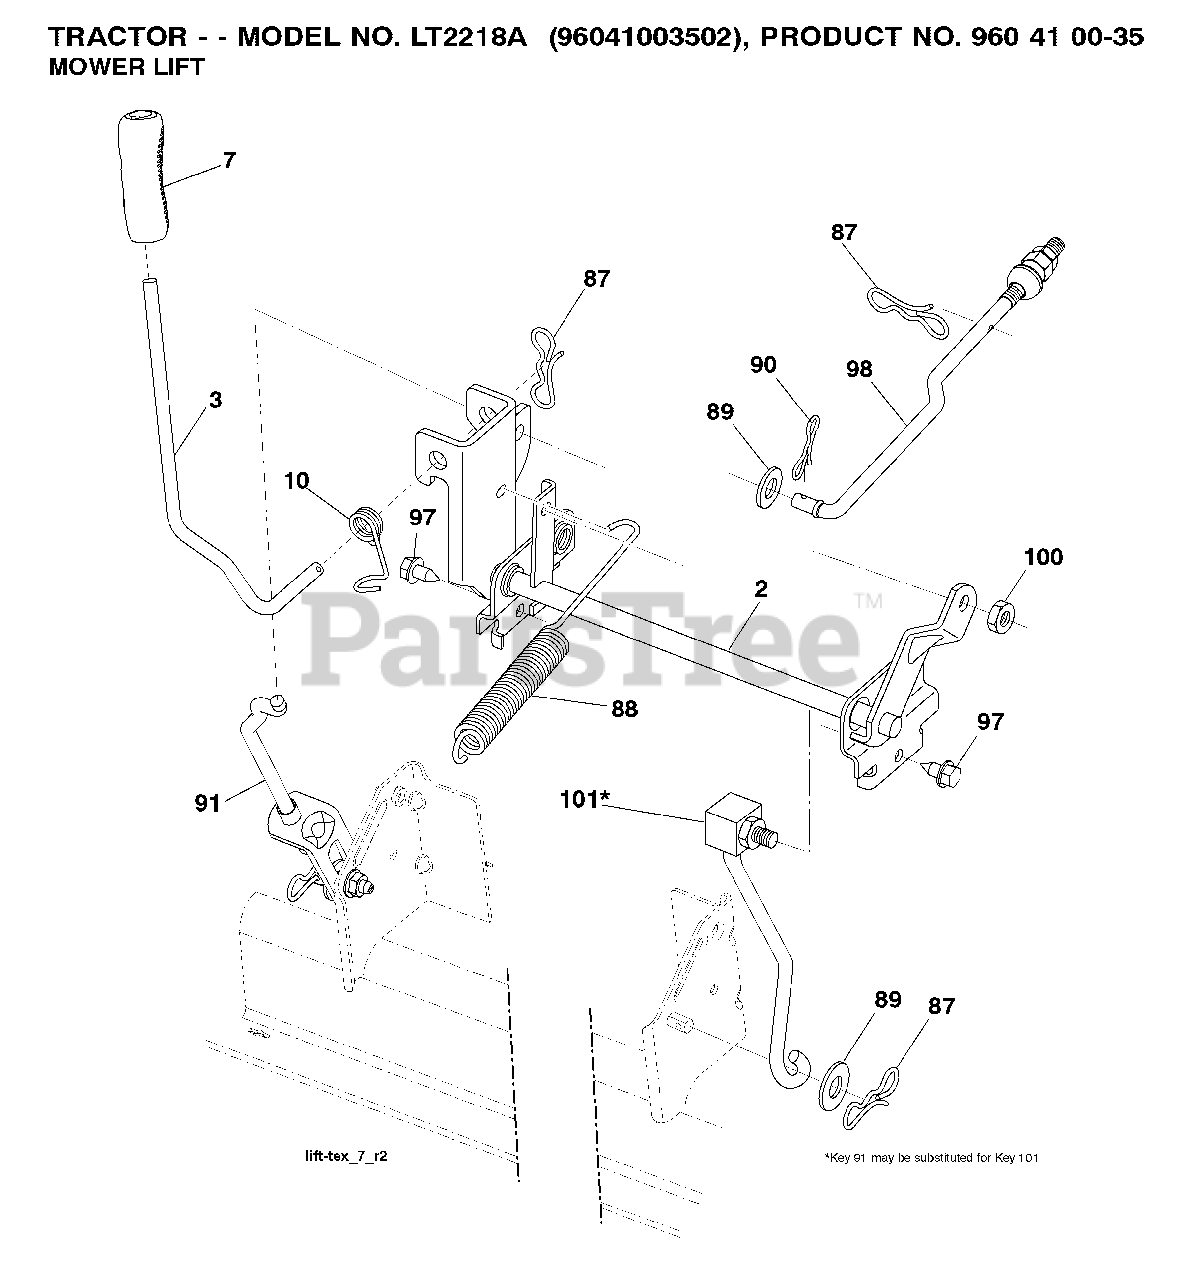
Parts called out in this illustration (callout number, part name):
2	SHAFT.ASM.LIFT.CROSS.H
3	LEVER.LIFT.HANDLE.LT
7	GRIP.HANDLE.LIFT.PVC.BLACK
10	SPRING.TORSION.LIFT.HANDLE
87	PIN.COTTER.7/16.BOW TI
88	SPRING.LIFT.ASSIST
89	WASHER.CLEAR.ZINC
90	PIN.COTTER.5/16.BOW TI
91	LINK.ASM.LIFT.REAR
97	SCREW, 3/8-16X3/4
98	LINK.ASM.SUSP.FRONT.MW
100	LOCKNUT
